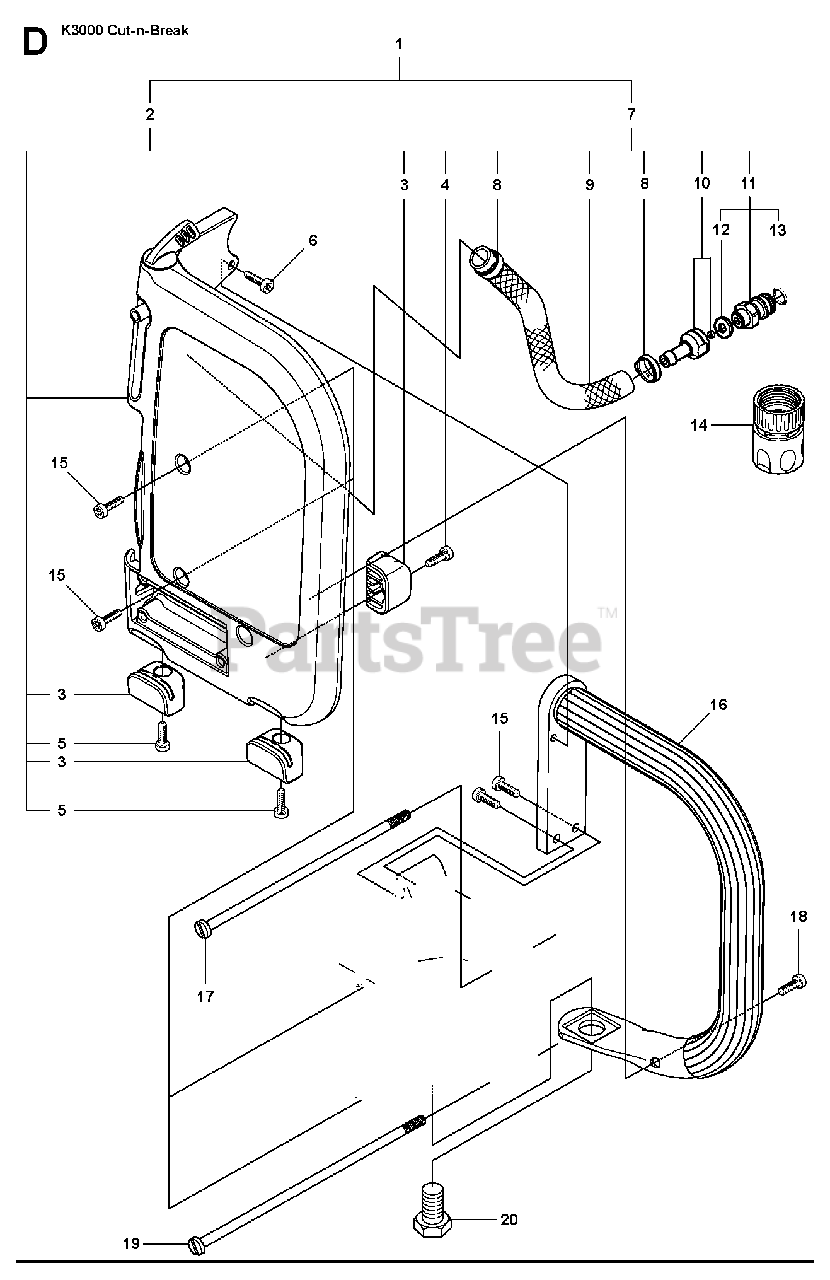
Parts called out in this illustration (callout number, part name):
4	SCREW ITXSCT
5	SCREW ITXSCT
6	SCREW ITXSCM
7	HOSE ASSYIncl. 8 - 12
8	HOSE CLAMP
11	NIPPLEIncl. 12, 13
15	SCREW ITXSCM
18	SCREW ITXSCT
